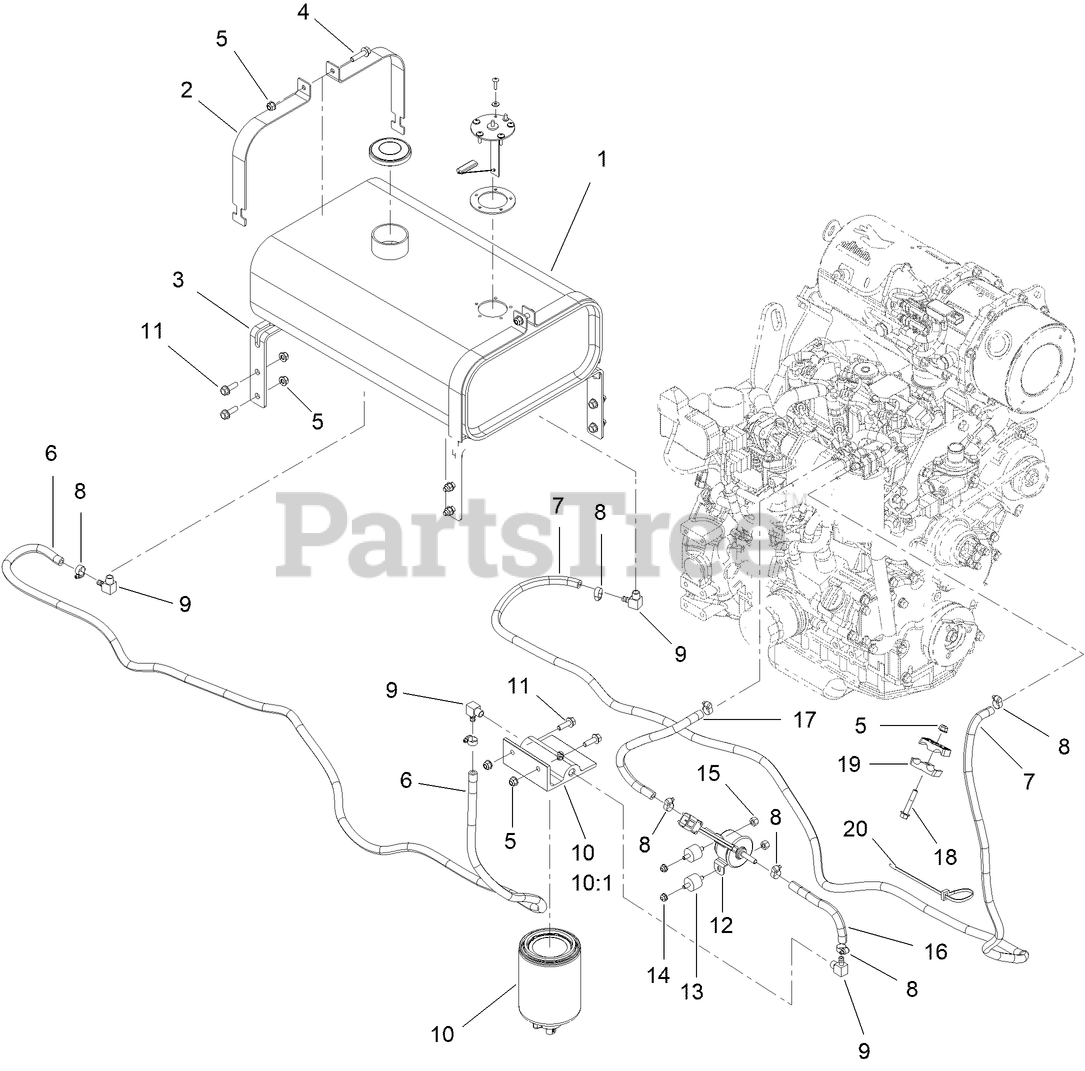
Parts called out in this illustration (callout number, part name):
3	BRACKET-FUEL TANK
4	SCREW-HHF
5	NUT-HF, NI
6	HOSE-FUEL
7	HOSE-FUEL
8	CLAMP-WORM
9	4/O COUPLER (04N-04H90)
10	SEPARATOR FILTER ASM
10:1	FILTER-FUEL/WATER SEPARATOR
11	SCREW-HHF
12	PUMP-FUEL, ELECTRIC
13	MOUNT-ISOLATER
14	NUT-HF
15	NUT-LOCK, NI
16	HOSE-FUEL
17	HOSE-FUEL
18	SCREW-HWH
19	CLAMP-TUBE
20	TIE-CABLE
